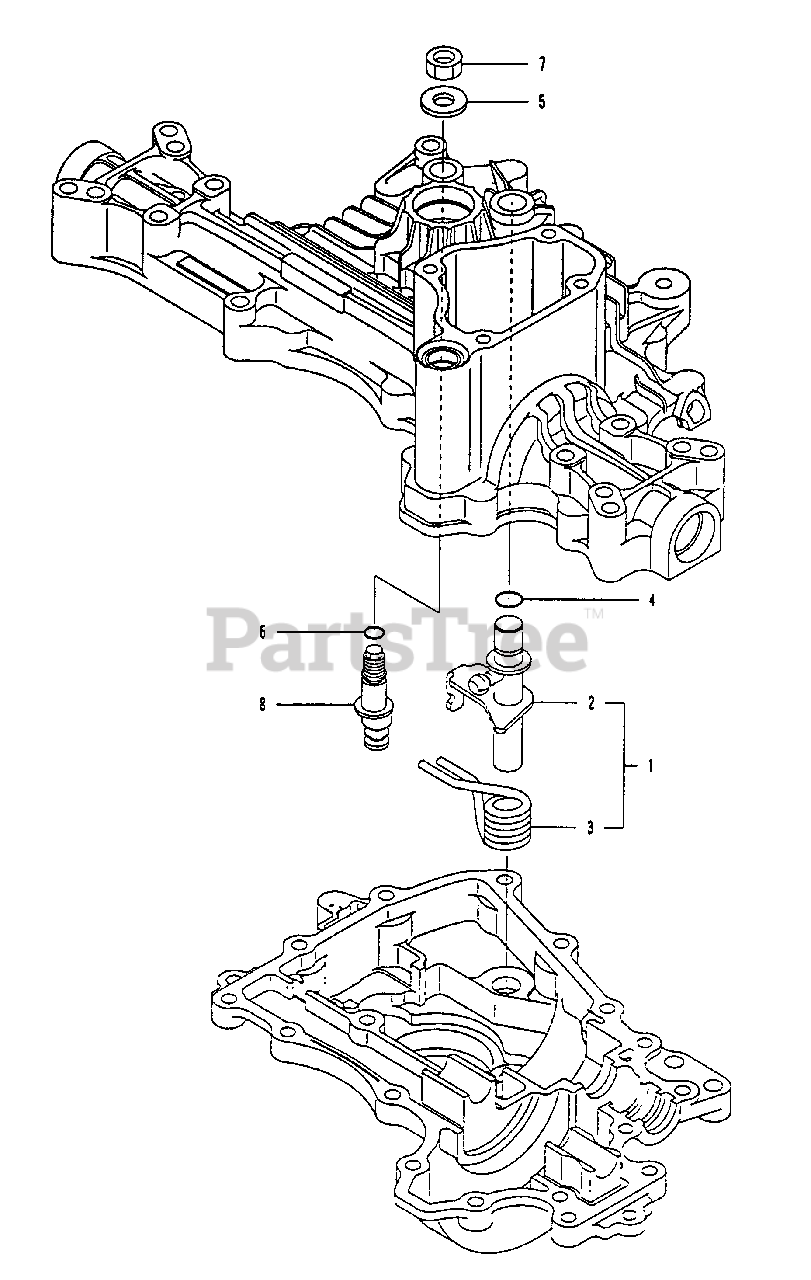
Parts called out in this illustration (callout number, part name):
1	CONTROL SHAFT CMP.
2	CONTROL SHAFT
3	SP (TORSION 630
4	PACKING P 12
6	PACKING P 10A
8	FULCRUM (ECCENTRICITY
